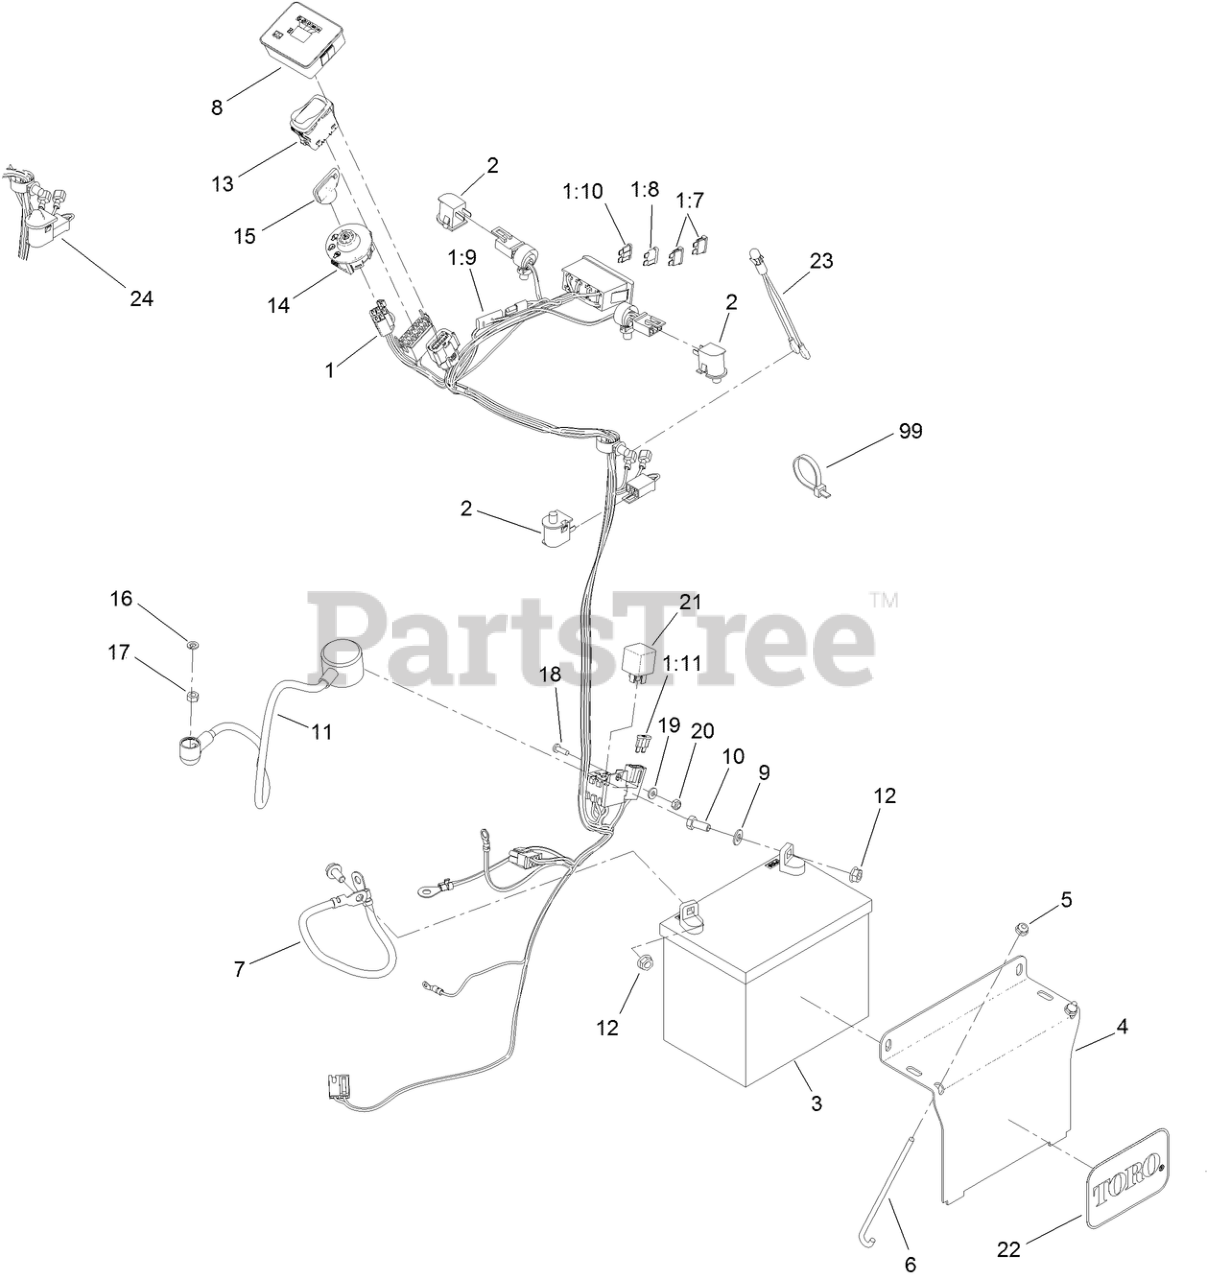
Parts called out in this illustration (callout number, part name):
1	HARNESS-WIRE, GRANDSTAND
1:7	FUSE-BLADE, 15 AMP
1:8	FUSE-BLADE, 10 AMP
1:9	CAP-PLUG
1:10	FUSE-BLADE, 7.5 AMP
1:11	FUSE-BLADE, 20 AMP
2	SWITCH-BAIL
3	BATTERY-DRY
4	BRACKET-HOLD DOWN, BATTERY
5	NUT-HF
6	BOLT-HOLDDOWN
7	CABLE-BATTERY, BLACK
8	MODULE-METER, HOUR
9	WASHER-PLAIN
10	SCREW-HH
11	CABLE-BATTERY, POSITIVE
12	NUT-HHF, SMOOTH
13	SWITCH-ROCKER, (ON)-ON-OFF
14	SWITCH-IGNITION
15	KEY-IGNITION
16	WASHER-LOCK
17	NUT-HEX
18	SCREW-PPH
19	WASHER-FLAT
20	NUT-LOCK, NI
22	DECAL
23	INDICATOR-LED, RED
24	SWITCH-PLUNGER
99	TIE-CABLE
